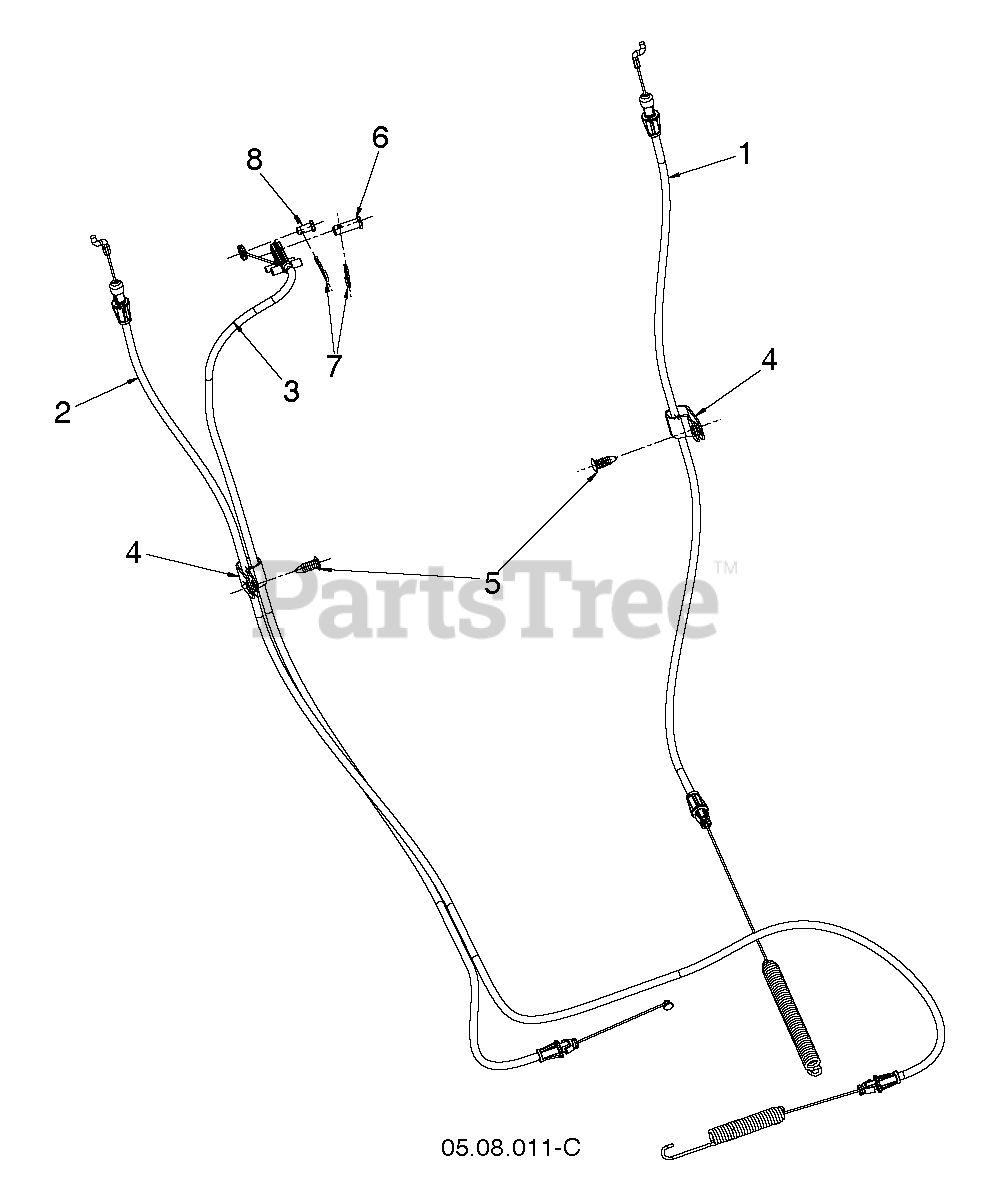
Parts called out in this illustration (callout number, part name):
1	CABLE.CONTROL.DRIVE.16
2	CABLE.CONTROL.AUGER
3	CABLE.CONTROL.SPEED.DSST.OPP
4	CLIP.CABLE.BLK
5	FASTENER.PUSH.O.250X0.783
6	PIN CLEVIS 5/16X.875
7	HAIRPIN.SOFT.ZINC.059X1.125
8	PIN CLEVIS .25 X .31
